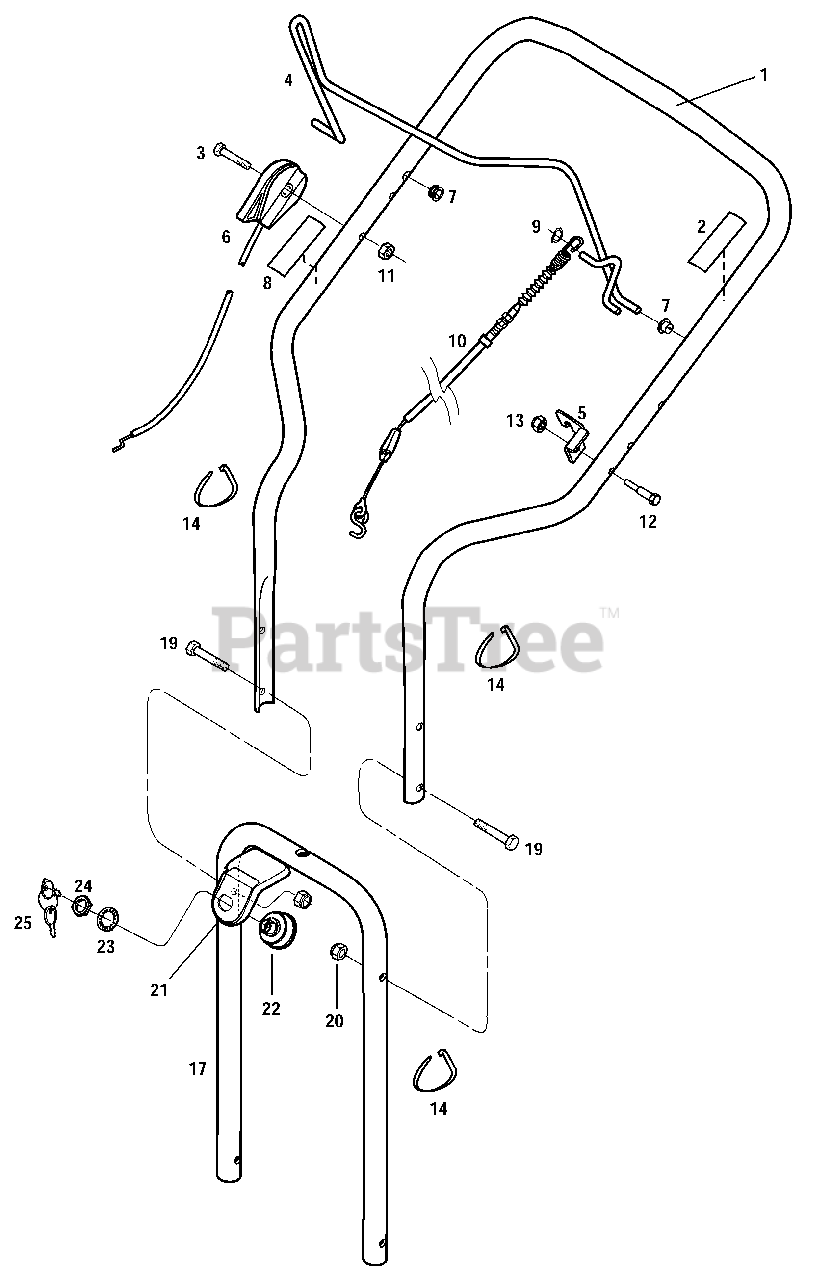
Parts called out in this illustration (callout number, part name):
1	Upper Handlebar
2	Decal-Bail Operation
3	Hex Hd. Screw, 1/4-20 x 2
4	Trimmer Head Control Bail
5	Cable Bracket
6	Throttle Control & Cable
7	Nyliner Bushing
8	Decal-Throttle Settings
9	Push Cap, .312 I.D.
10	Trimmer Head Control Cable
11	Hex Lock Nut, 1/4-20
12	Hex Hd. Screw, 1/4-20 x 1-1/8
13	Hex Flange Lock Nut, 1/4-20
14	Cable Tie
17	Lower Handlebar
19	Hex Hd. Screw, 5/16-18 x 1-1/2, Gr. 5
20	Lock Nut, 5/16-18
21	Decal - Keyswitch
22	Keyswitch
23	Lockwasher, 5/8
24	Hex Nut, 5/8-32
25	Key
